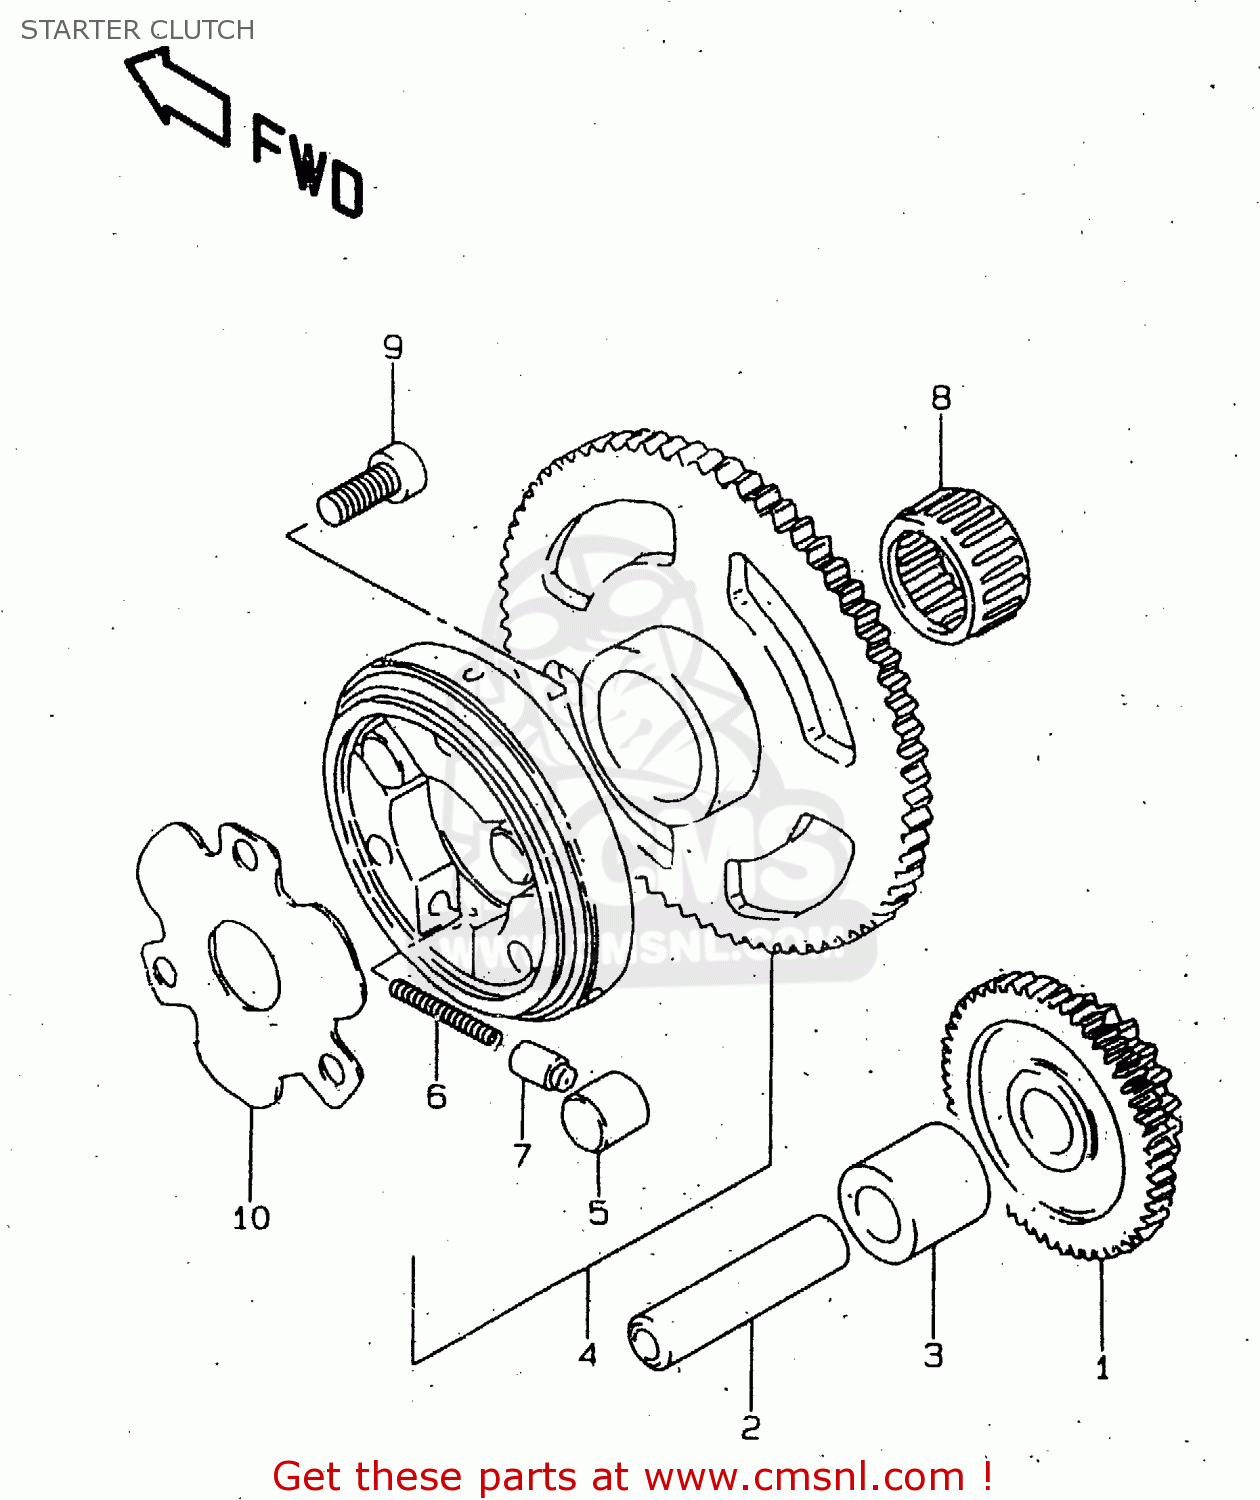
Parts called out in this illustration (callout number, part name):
1	GEAR,STARTER IDLER
2	PIN(7.4X13X56)
3	SPACER(13X19X19)
4	CLUTCH SET,STARTER
5	ROLLER(10X11)
6	SPRING
7	PIECE,STARTER CLUTCH PUSH
8	BEARING(22X28X16)
9	BOLT,OIL FILLE
10	SHIM,STARTER CLUTCH HUB
